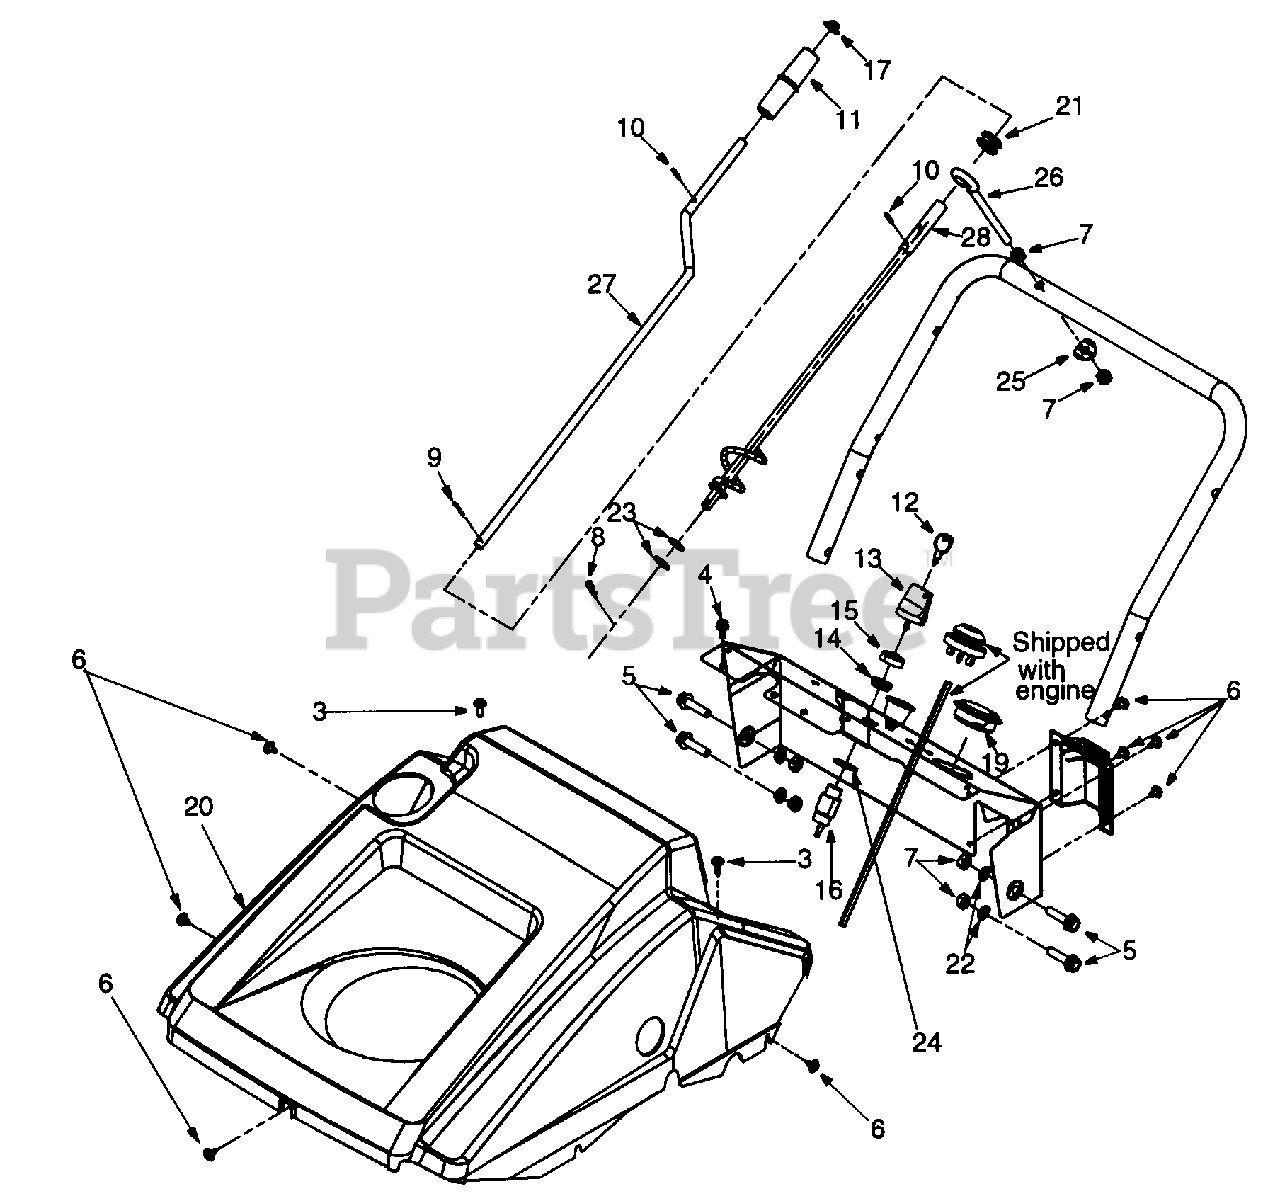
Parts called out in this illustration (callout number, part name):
1	Dash: 21" Mitten Panel Assy.
2	Chute Crank Assembly
3	Special Screw
4	B Screw 1/4-14 x 0.5"
5	Hex Flange Screw
6	Special Screw
7	Hex Nut: 5/16-18
8	Cotter Pin
9	Cotter Pin
10	Roll Pin
11	Chute Crank Knob
12	Ignition Key
13	Ignition Key w/o Logo
14	Ignition Switch Nut
15	Ignition Switch Cap
16	Switch: Key Recoil Start
17	Push Cap
18	Choke Cover
20	Engine Shroud: Grey
21	Rubber Grommet
22	Lock Washer
23	Flat Washer
24	Internal Lock Washer
25	Saddle Washer
26	Eye Bolt
27	Chute Crank: Upper
28	Spacer
